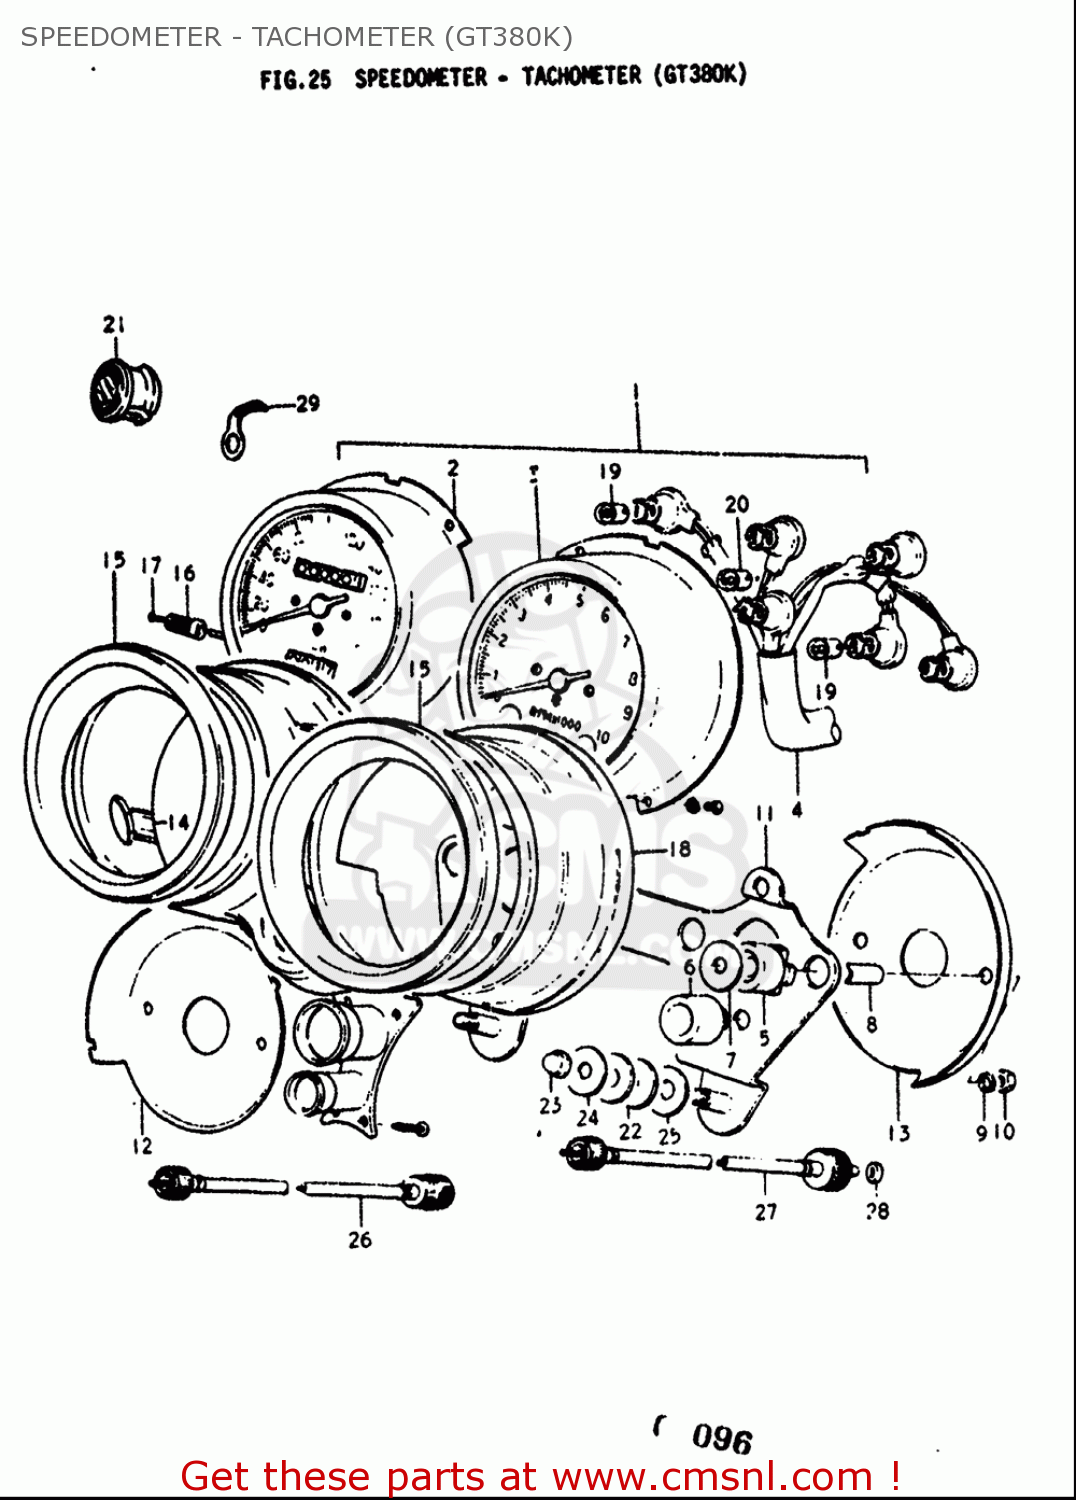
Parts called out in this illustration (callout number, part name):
5	CUSHION,METER NO.1
6	CUSHION,METER
9	WASHER,LOCK
10	NUT
14	CAP
15	VISOR
16	KNOB, TRIP METER
17	SCREW(2X6)
19	BULB(12V3.4W,STANLEY,A72A)
20	BULB(12V1.7W,A71A)
21	CAP,SPEED WARNER LAMP HOLE
22	CUSHION
23	NUT
24	WASHER
25	WASHER(6.5X18X1.6)
26	CABLE ASSY,SPEEDOMETER
27	CABLE ASSY,TACHOMETER
28	SEAL,OIL SPEEDOMETER CABLE
29	LAMP ASSEMBLY
